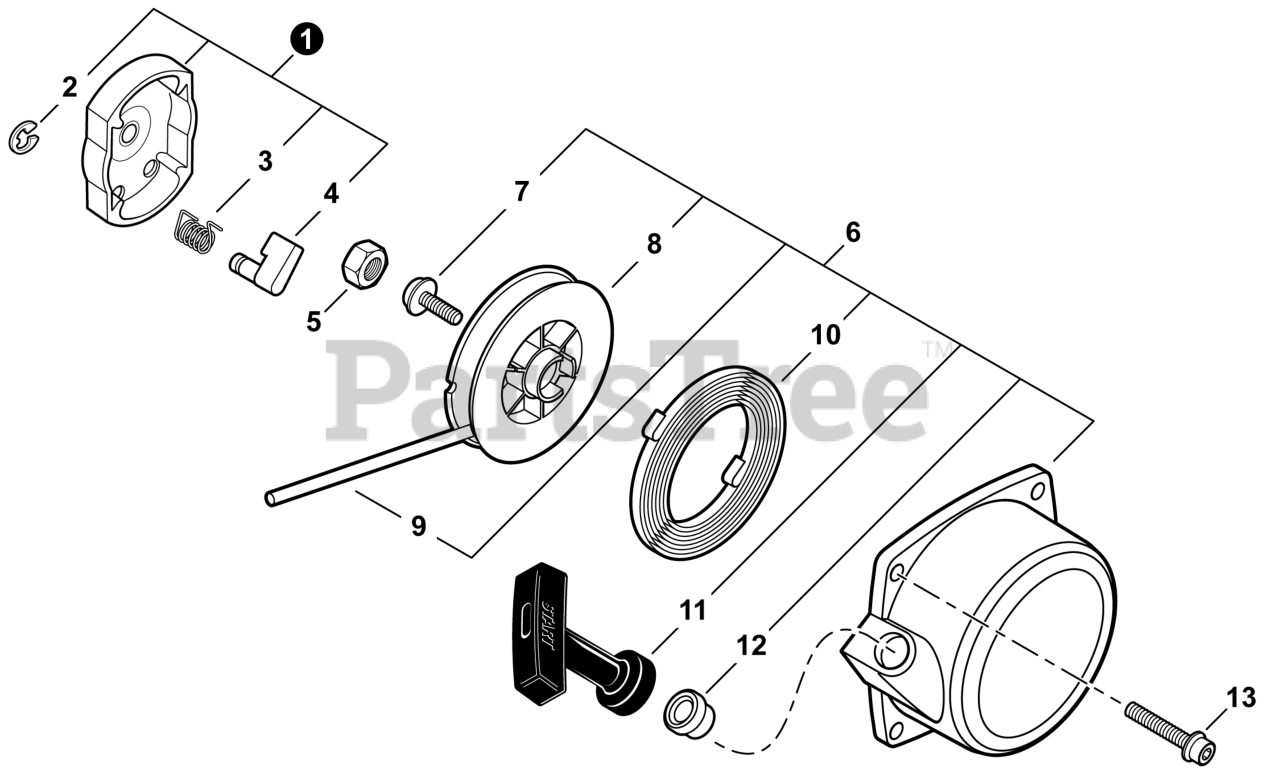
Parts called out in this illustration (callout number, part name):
1	PAWL ASSY, STARTER
2	E-RING 4
3	SPRING, RETURN
4	PAWL, STARTER
5	NUT 8x1.25
6	STARTER ASSY, RECOIL
8	REEL, ROPE
9	ROPE, STARTER 3.8x1150
10	SPRING, RECOIL
11	GRIP, STARTER
12	GUIDE, ROPE
13	BOLT 5x20
